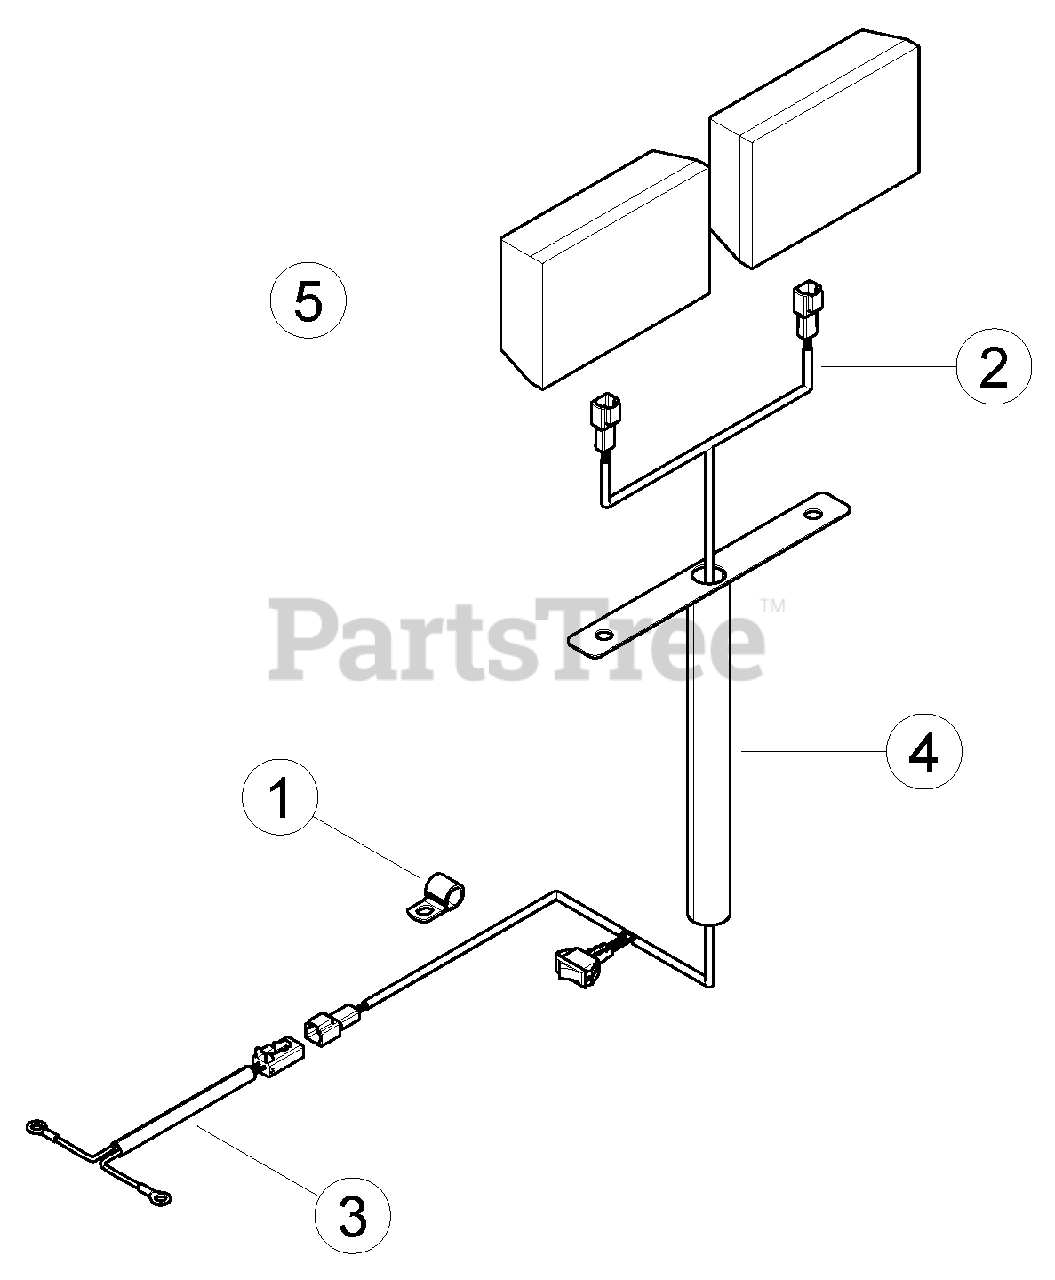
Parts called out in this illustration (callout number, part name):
1	CLAMP, 9/16 COATED
2	HARNESS, DEUTSCH TO DEUTSCH
3	HARNESS, DEUTSCH TO RING
4	WELDMENT, MOUNT LIGHTS
5	LAMP, 4 X 6 HALOGEN W DEUTSCH
